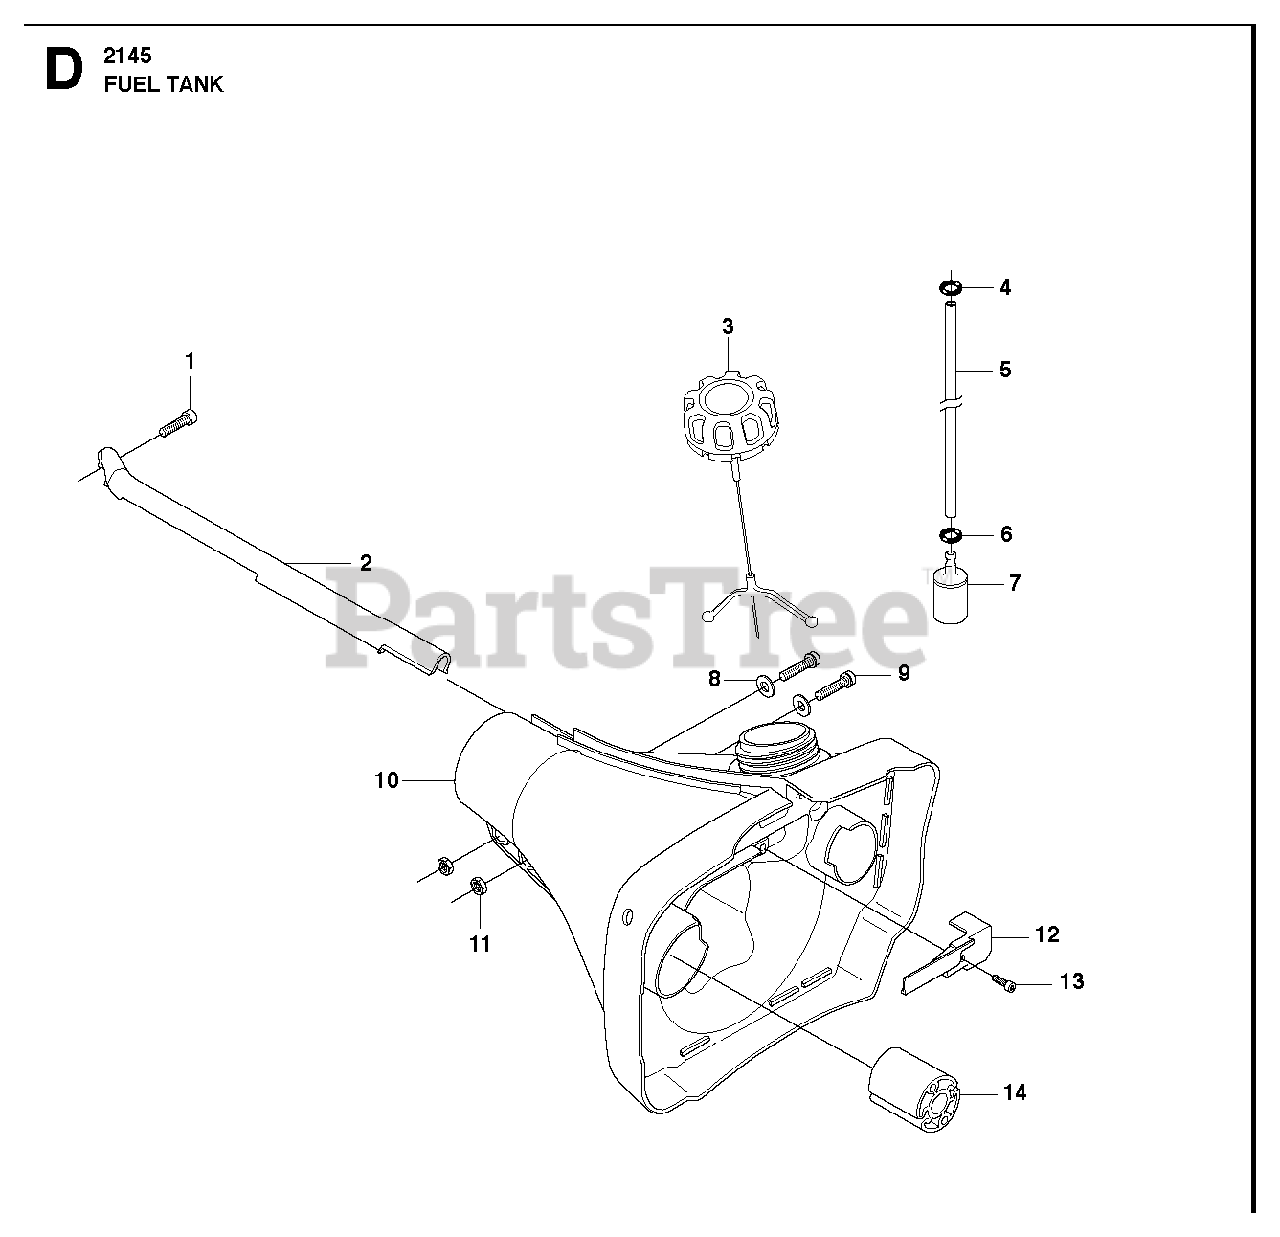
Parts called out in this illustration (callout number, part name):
2	TUBE (FC,FCS)
2	TUBE (BC)
3	%WINTER TANK CAP
5	FUEL HOSE
7	FUEL FILTER
8	WASHER 5.3X12
10	TANK UNIT
14	%BELLOWS
